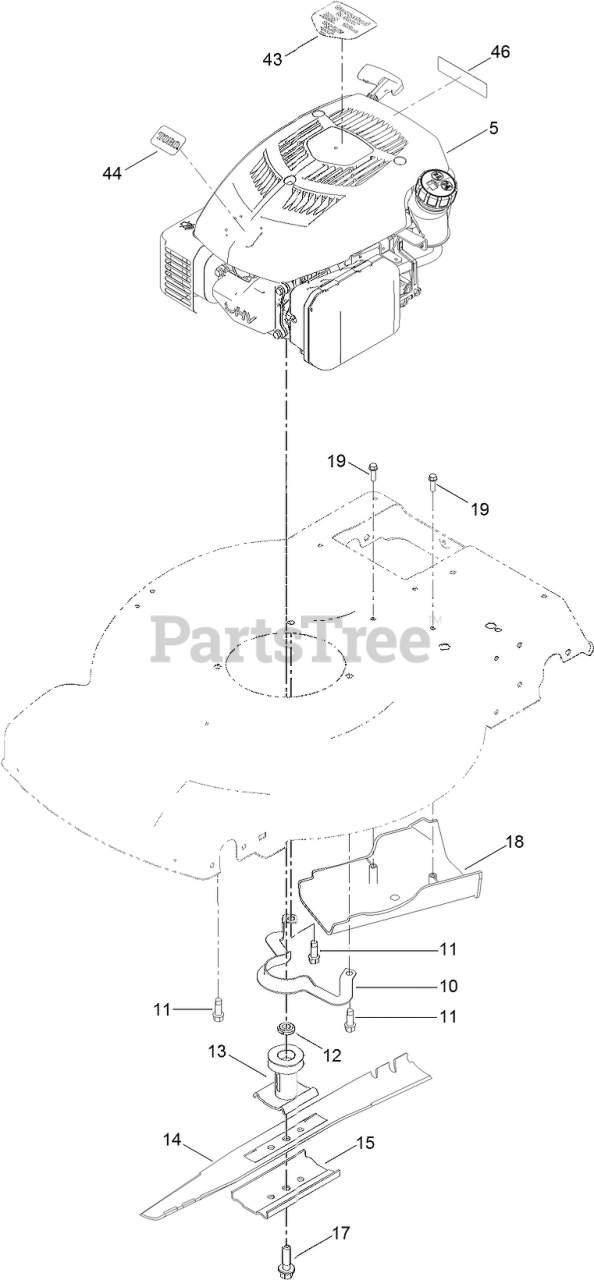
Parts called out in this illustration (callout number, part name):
5	ENGINE-1P65F-2
10	GUIDE-BELT
11	SCREW-TAPTITE
12	SPACER-DRIVER
13	DRIVER-BLADE
14	BLADE-22 INCH
15	SUPPORT-BLADE
17	BOLT-BLADE
18	COVER-BELT
19	SCREW-HWH
43	DECAL-SHROUD
46	DECAL-ARRESTOR, SPARK
